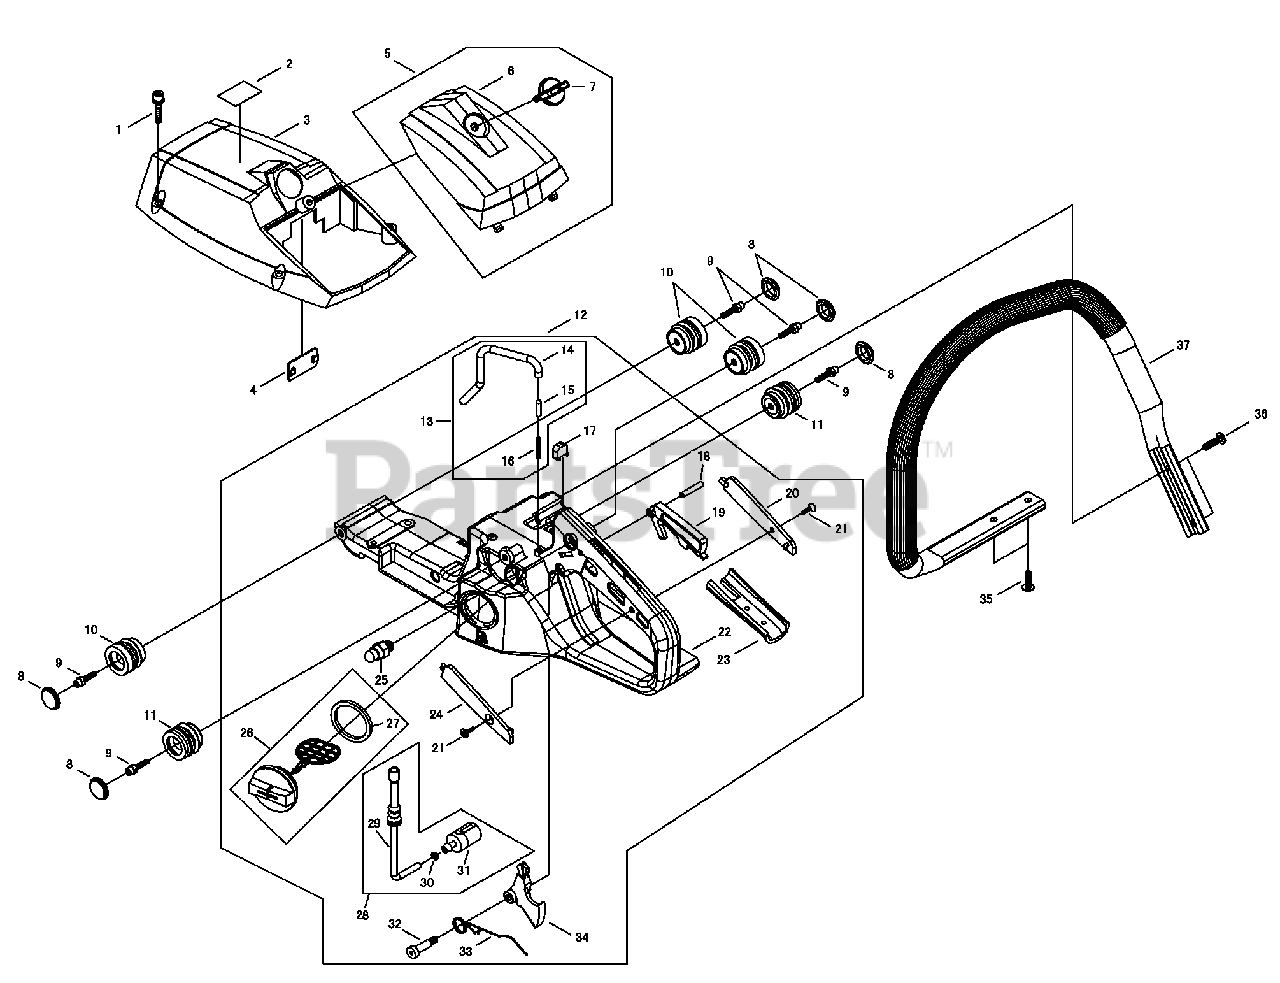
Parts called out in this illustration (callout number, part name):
1	BOLT
2	LABEL - CAUTION
3	COVER, ENGINE
4	PLUG
5	AIR FILTER COVER ASSY
6	COVER, AIR FILTER
7	THUMBSCREW
8	CAP, CUSHION
9	BOLT
10	CUSHION
11	CUSHION
12	REAR HANDLE SUB ASSY
13	VENT, FUEL TANK
14	PIPE - VENT
15	ELEMENT
16	SPRING
17	STOPPER R
18	PIN - SPRING -- 4X25
19	LEVER, LOCK
20	PLATE - RIGHT
21	SCREW
22	HANDLE - REAR
23	GRIP
24	PLATE - LEFT
25	LOCK, THROTTLE
26	CAP ASSY
27	GASKET, CAP
28	FUEL PIPE ASSY
29	PIPE - FUEL
30	CLIP - 6
31	FILTER, FUEL
32	BOLT
33	SPRING, LEVER
34	TRIGGER, THROTTLE
35	BOLT - TAPPING
36	SCREW - 5X20
37	HANDLE - FRONT
